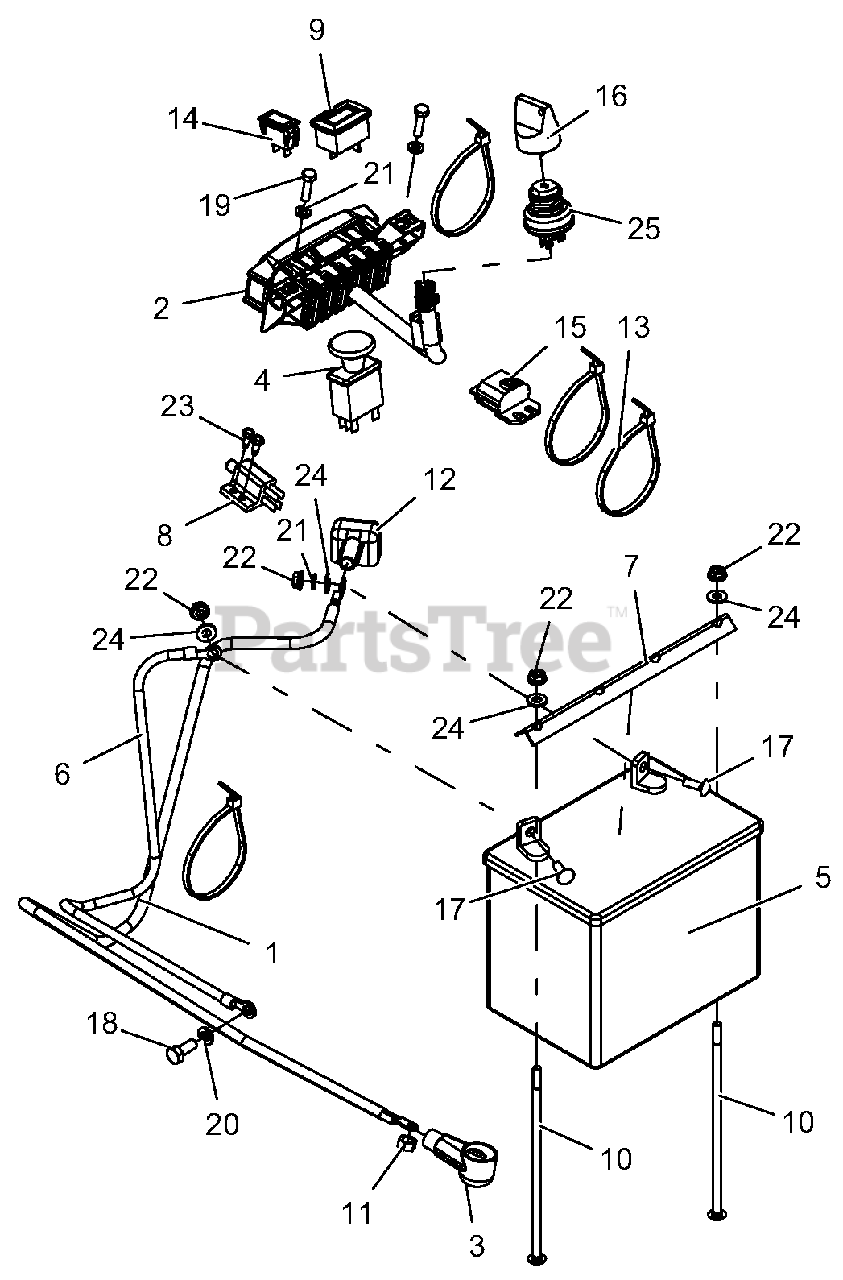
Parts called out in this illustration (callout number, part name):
1	CABLE, BATTERY - 42" POSITIVE
2	HARNESS, WIRE - HARNESS
3	BOOT, BATTERY TERMINAL - RED
4	SWITCH, CLUTCH
6	CABLE, NEGATIVE BATTERY 35.00"
7	HOLD DOWN - BLK
8	SWITCH- DOUBLE POLE N.O./N.O.
9	METER, HOUR W/MAINTENANCE
10	BLT-RDHDSQNK .250-20 x 7.50 GR2 YZ
11	NUT-LK-TOP M8-1.25 YWZC
12	INSULATOR
13	CABLE, TIE 5.50 LG
14	LIGHT, INDICATOR
15	MODULE, INTERLOCK
16	KEY, W/ COVER
17	BLT-RDHDSQNK .25-20 x .75 G5 YWZC
18	@BLT-HEX M8-1.25 x 20 YWZC
19	@BLT-HEX M6-1.0 x 25 YWZC
20	WSHR-LK .31 x .078 REG YWZC
21	WSHR-LK .25 x .062 REG YWZC
22	@NUT-SPNLK-FLG .25-20 YWZC
23	SCR-TAP 10-24 x .50 HWH TR YWZC
24	WSHR-FL-STL .281 x .62 x .065 YWZC
25	SWITCH, IGNITION
